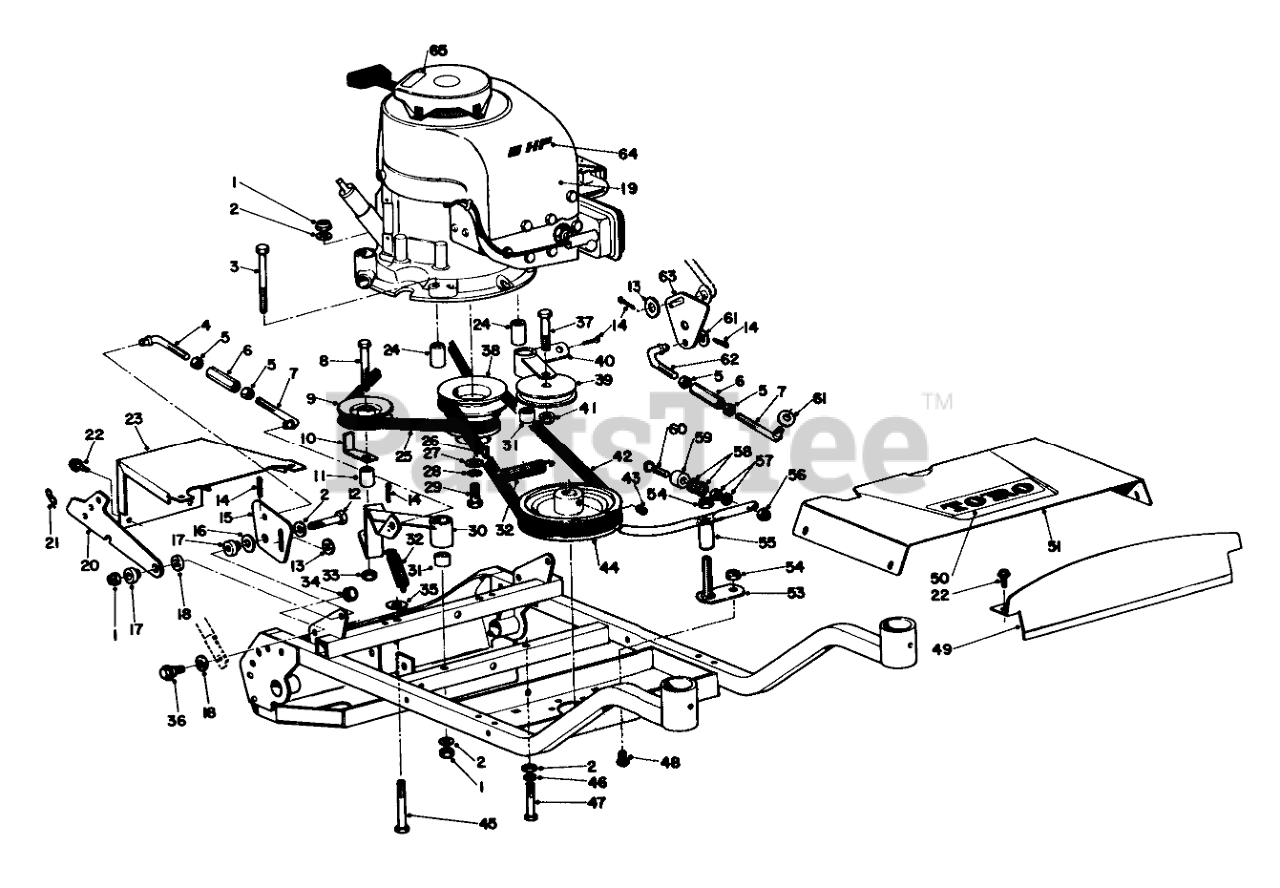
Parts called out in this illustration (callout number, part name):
1	Nut
2	WASHER-PLAIN
3	SCREW-HH
4	TRACTION LINK
5	NUT-HEX
6	CONTROL ROD SLEEVE
8	SCREW-HH
9	IDLER PULLEY R
11	SPACER
12	5/16-18 X 1-3/4 SCREW
13	Spacer
14	PIN-COTTER
15	Bell Crank
16	WASHER
17	PIVOT
18	SPACER
19	Engine
20	Latch
21	PIN-COTTER
22	10-16 X 3/8 THDG SCREW
23	Rear Shroud
24	ENGINE PIVOT SPACER
25	V-BELT
26	KEY-WOODRUFF
27	WASHER-FLAT
28	WASHER-LOCK
29	SCREW-HH
30	Arm & Bushing (Incl. Ref. #31)
31	BUSHING
32	EXTENSION SPRING
33	NUT-HEX
34	Nut
35	WASHER
36	SCREW-SHOULDER
37	Screw
38	ENGINE PULLEY RO
39	PULLEY B
40	Arm & Bushing (Incl. Ref. #31)
41	Nut
42	CUTTER BELT
43	SCREW-HSH
44	CUTTER PULLEY
45	SCREW-HH
46	WASHER-LOCK
47	SCREW-HH
48	SCREW-CARR
49	Shroud Panel
50	Decal
51	FRONT SHROUD R
53	Base Pivot
54	NUT-HEX
55	Brake Arm
56	NUT-LOCK, NI
57	NUT-HEX
58	WASHER-FLAT
59	BUMPER
60	10-24X1-1/2 RND HD MS
61	WASHER
62	CUTTER LINK
63	CUTTR BELLCRANK WA R
64	Decal
65	Decal Caution
